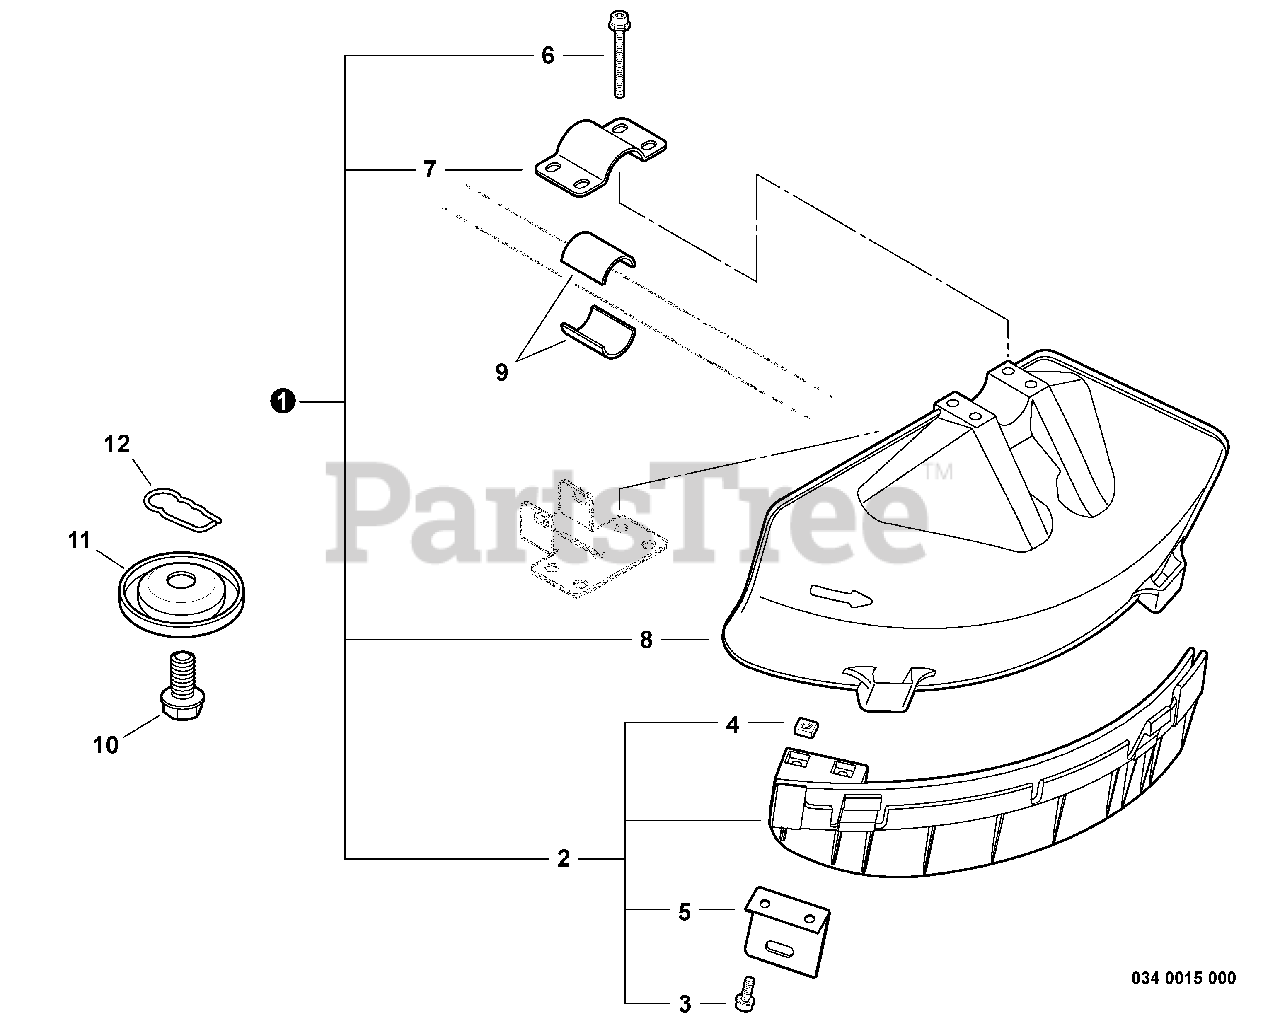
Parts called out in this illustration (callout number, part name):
1	DEBRIS SHIELD KIT - PLASTIC
2	SHIELD GUARD KIT
3	SCREW - 5X16
4	NUT - 5
5	KNIFE, TRIMMER LINE
6	SCREW - 5X45
7	CLAMP - UPPER
8	SHIELD, DEBRIS
10	BOLT - 8 -- LEFT HAND
12	CLIP
